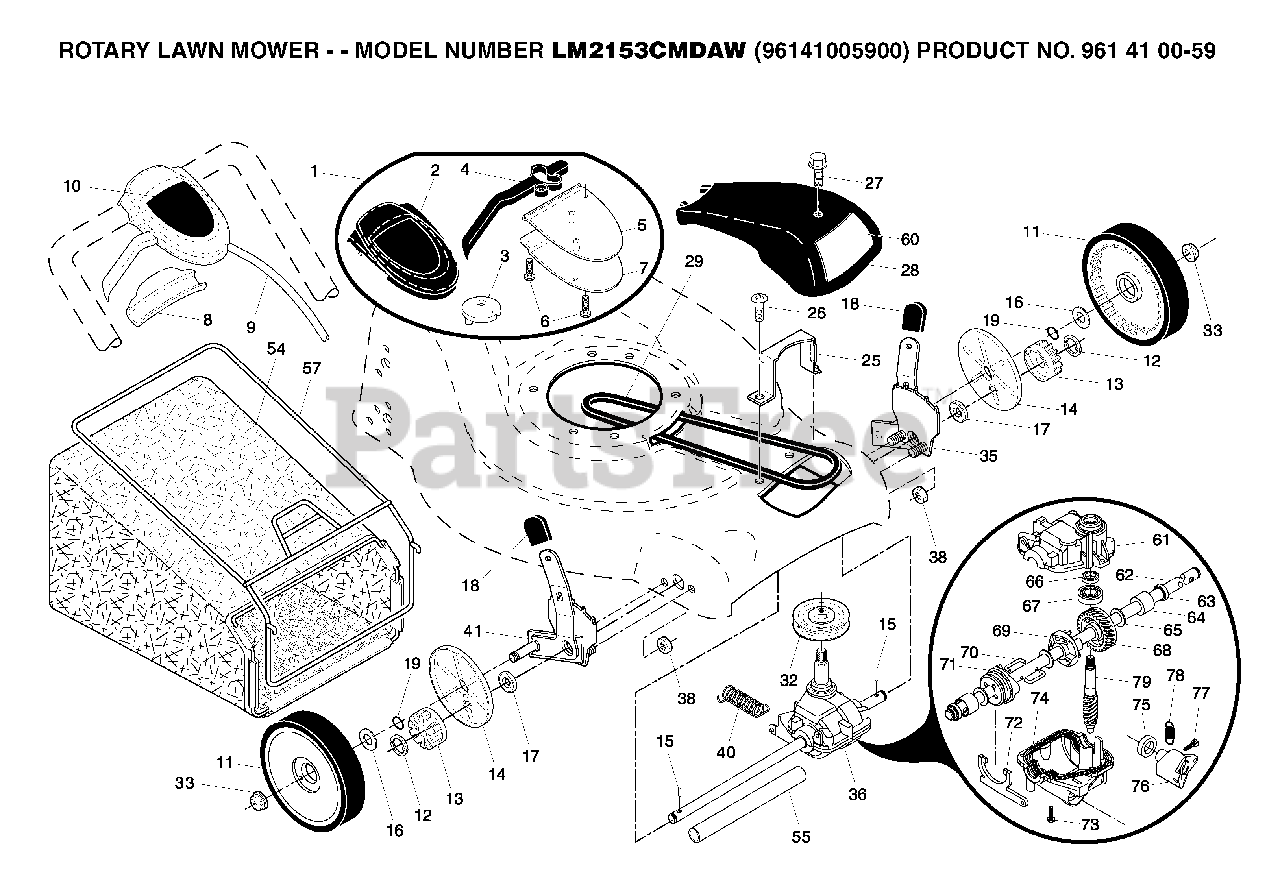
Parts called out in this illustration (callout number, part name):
3	PULLEY, DRIVE CONTROL
6	SCREW, PHILLIPS HEAD 10 X 5/8
7	BRACKET.DRIVE.CONTROL.MOUNT
8	EA WLK COVER PLATE.BLK
9	CABLE.ASM.
12	E-RING 7/16 RE
13	PINION
14	COVER.DUST.WHEEL
15	PAWL.DRIVE
16	WASHER FLUT
17	BEARING
18	SELECTOR KNOB
25	KEEPER.BELT.21.EZ.FWGD
26	SELF-TAPPING SCREW 5/16-18X3/4
27	SCREW, HEX HD TAPPING #10-24 1
29	BELT.DRIVE.FGD.
32	RP PULLEY.DRIVE.EZ
33	HEX FLANGE LOCKNT
35	RP KIT.ADJUSTER.ASM.EZ
36	TRANSMISSION.21RD
38	LOCKNUT
40	SPRING RETURN
41	KIT.ADJUSTER.AS.EZ RT
54	GBAG.34710010.BLACK.GE
55	DRIVESHAFT COVER
57	FRAME.GBAG.21.FWGD.
61	GEARCASE.HOUSING
62	SHAFT.OUTPUT
63	SEAL.OUTPUT.SHAFT
66	SEAL INPUT SHAFT
68	GEAR.27.TEETH.WALK.MOWER
70	WIRE, FORMED
74	GEARCASE.HOUSING
77	SCREW.LEVER.
79	SHAFT, INPUT
